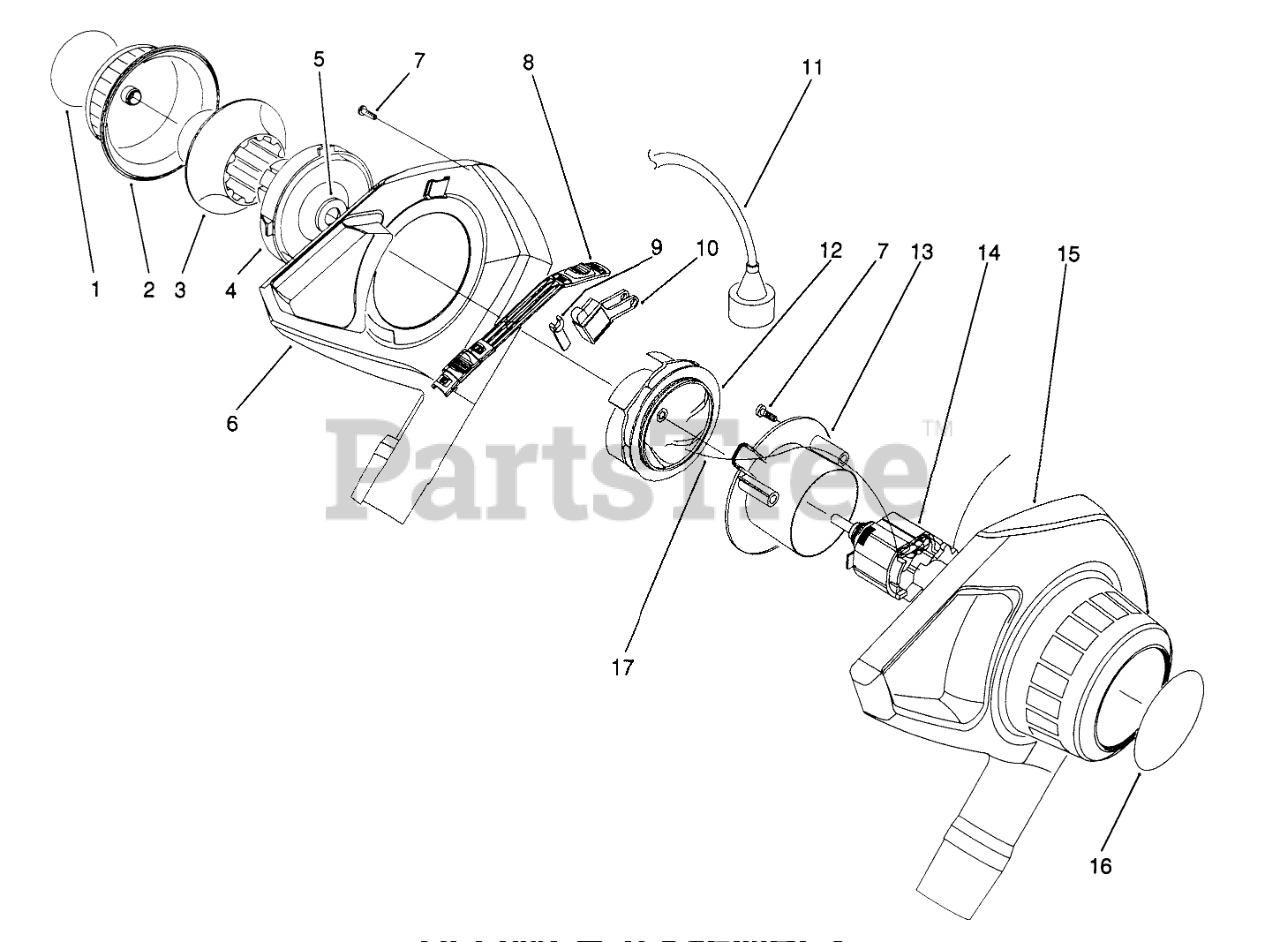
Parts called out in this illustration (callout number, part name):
1	DECAL, 700 CHOKE
2	CHOKE COVER, 600/700
3	MID BL-RING CHOKE
4	MID BL-BASE CHOKE
5	Clip-Retainer
6	HOUSING ASSY, RH
8	SWITCH BAR, 600/700
9	MID BL-ACTUATOR
10	Switch
11	POWER SUPPLY CORD
12	Impeller Assembly
13	RETAINING PLATE
14	Motor
15	HOUSING, LH
16	SERIAL DECAL 700
